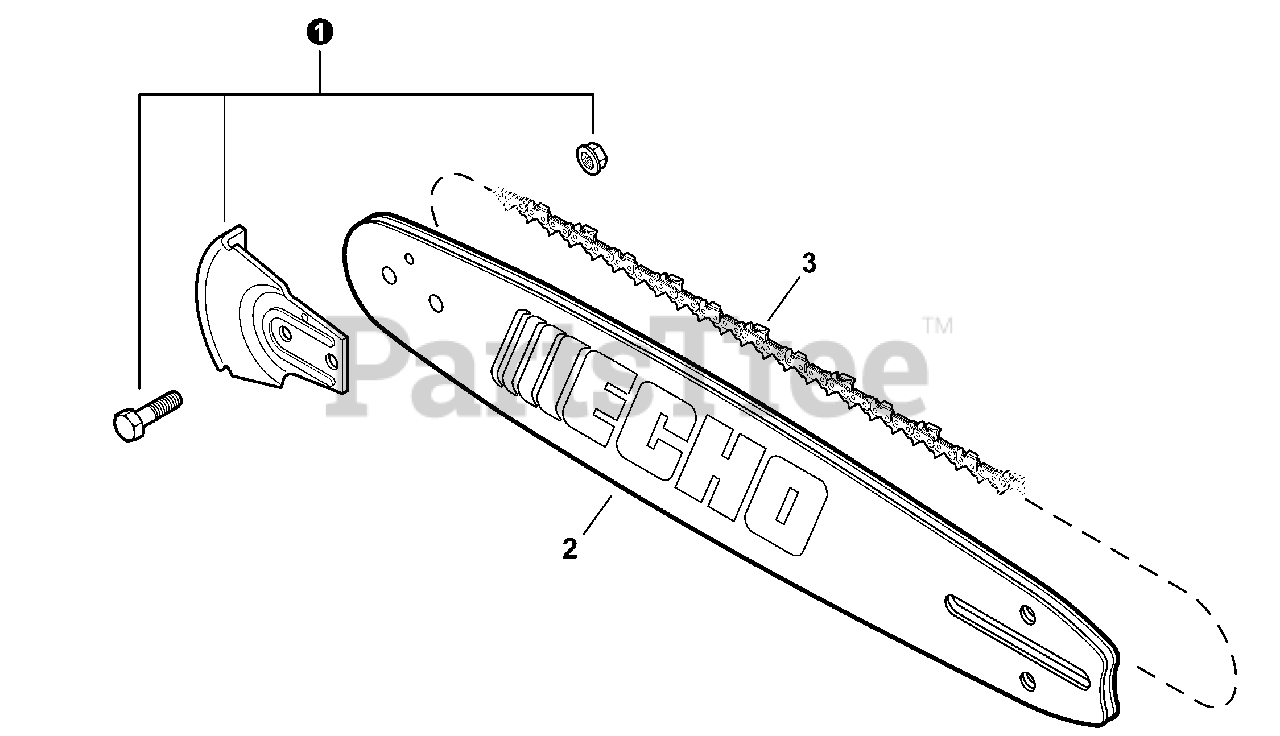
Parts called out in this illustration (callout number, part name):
1	KICK GUARD KIT
2	GUIDE BAR, 14" (.050" Ga)
2	GUIDE BAR, 16" (.050" Ga)
2	GUIDE BAR, 18" (.050" Ga)
3	SAW CHAIN 14" (.050" Ga)
3	SAW CHAIN 16" (.050" Ga)
3	SAW CHAIN 18" (.050" Ga)
